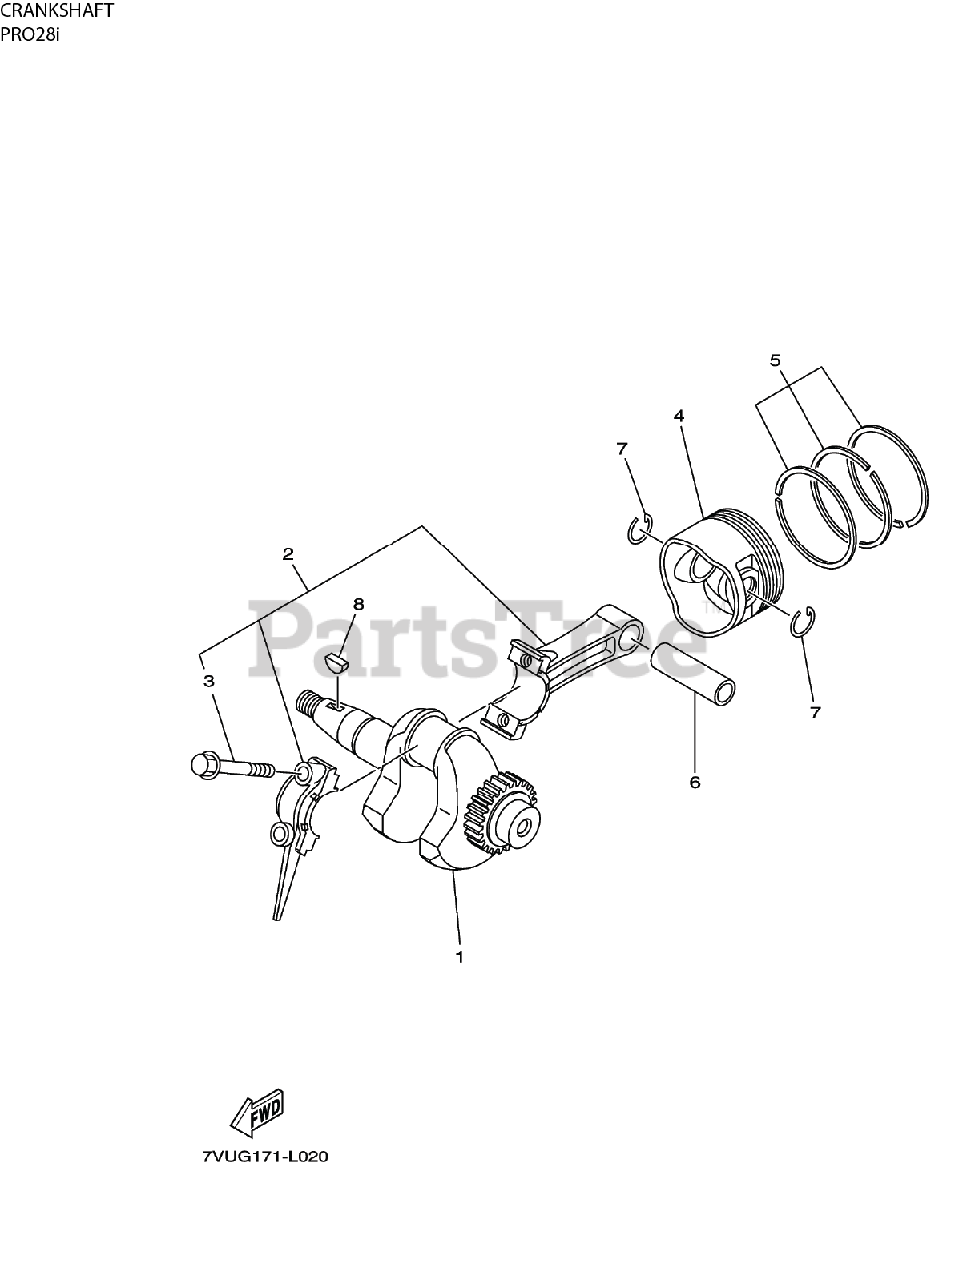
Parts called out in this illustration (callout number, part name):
1	CAMSHAFT ASSEMBLY
2	ROD ASSEMBLY, CONNECTING
3	SCREW - BOLT CONNECTING ROD
4	PISTON (0.50MM O/S)
4	PISTON (0.25MM O/S)
4	PISTON (STD)
5	PISTON RING SET
6	PIN, PISTON
7	RETAINER, CIRCLIP
8	KEY, WOODRUFF
